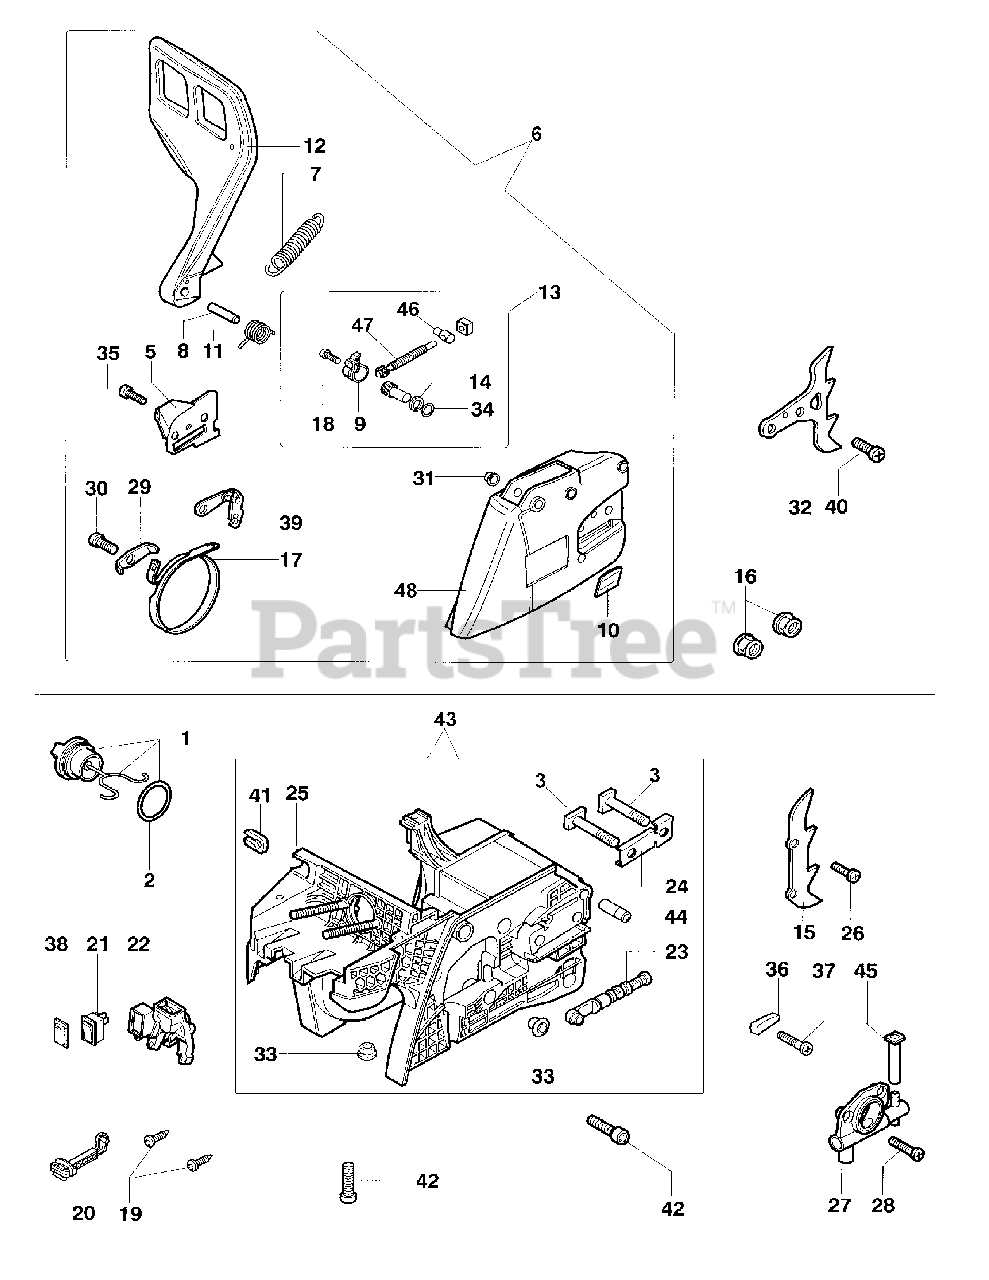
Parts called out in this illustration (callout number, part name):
6	COVER ASSEMBLY
13	CHAIN
20	STARTER LEVER
21	SWITCH
22	FILTER ATTAC.
38	SWITCH GUARD
44	TANKBREATHER
46	TENSIONING NUT
47	ADJUSTING SCREW
48	CHAIN COVER
